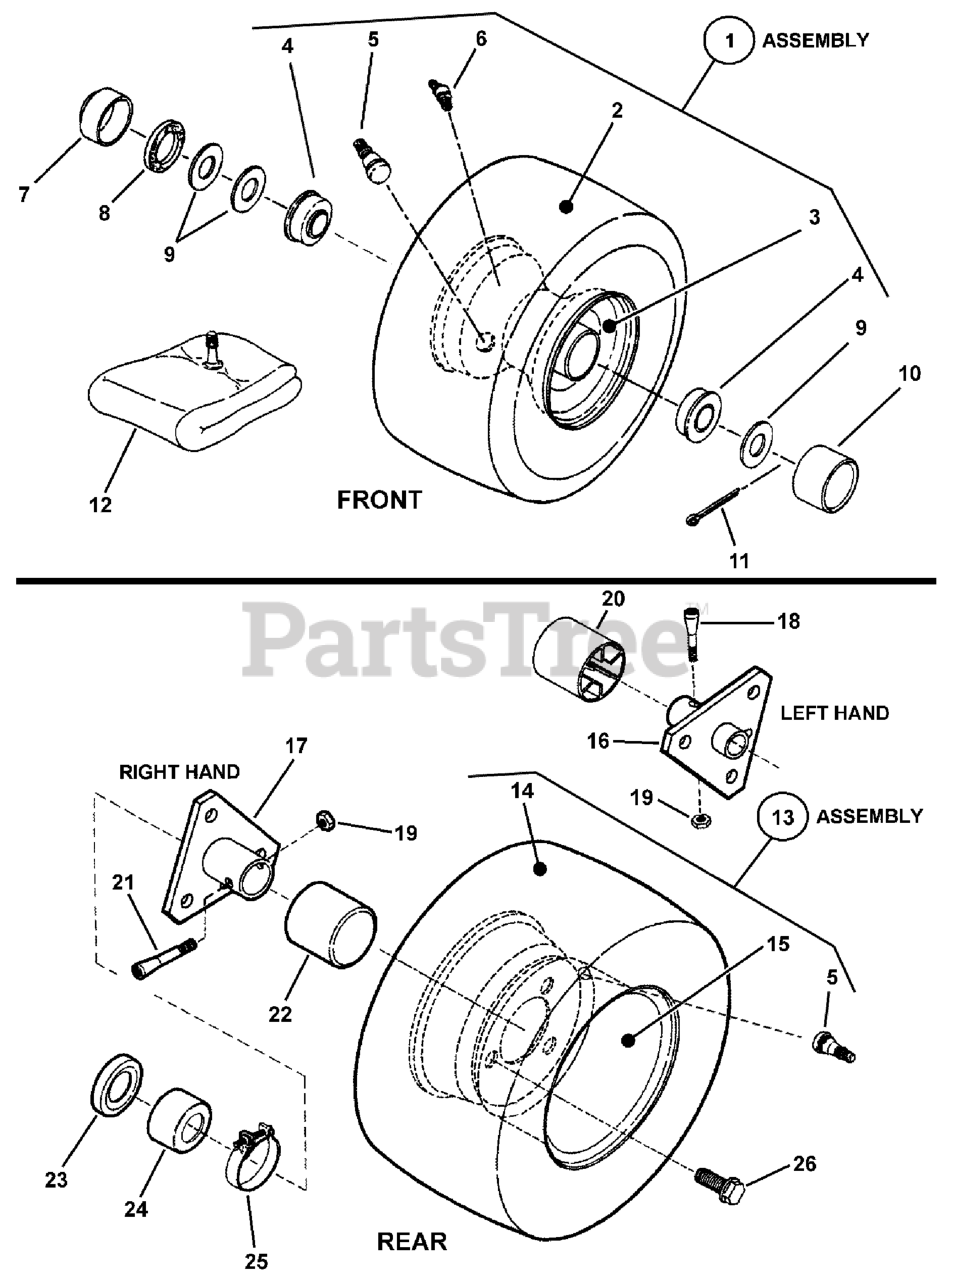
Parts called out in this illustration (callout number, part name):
1	ASSEMBLY, Front Tire & Rim Complete
2	TIRE, 11 x 4.00-4 (Kenda)
3	RIM (For 4.10/3.50 x 4 Tire)
4	BALL BEARING, Flange (3/4" I.D.)
5	VALVE STEM, Snap In
6	LUBE Fitting
7	CAP, Dust
8	FELT SEAL
9	WASHER, .77 x 1.13 x .06 Flat
11	COTTER PIN, 5/32 x 1"
12	TUBE, Inner (For 4.10/3.50 x 4 Tire)
13	ASSEMBLY, Rear Tire & Rim (28", 30", 33" Models)
14	TIRE, 16-6.50 x 8
15	RIM, Extra Wide (For 16/7.50 x 8 Tire) (33" Models)
16	HUB, Rear Wheel LH, 3 Hole 3/4" ID
17	HUB, Rear Wheel RH, 3 Hole 1" ID
18	AXLE BOLT, Left Hand (5/16-24 x 1-5/8" Tapered)
19	NUT, Wheel Bolt, 5/16-24 Hex Center Lock
20	CAP, Hub, L. H. (Long Axle)
21	WHEEL BOLT, Right Hand (5/16-24 x 2" Tapered)
22	CAP, Hub
23	SEAL, 1.22" ID x 1.875" OD
24	CAP, Seal 1.0" ID x 1.67" OD, Right Hand
25	CLAMP, Right Hand 2"
26	BOLT, 1/2-20 x 3/4" Lug, GR 5
